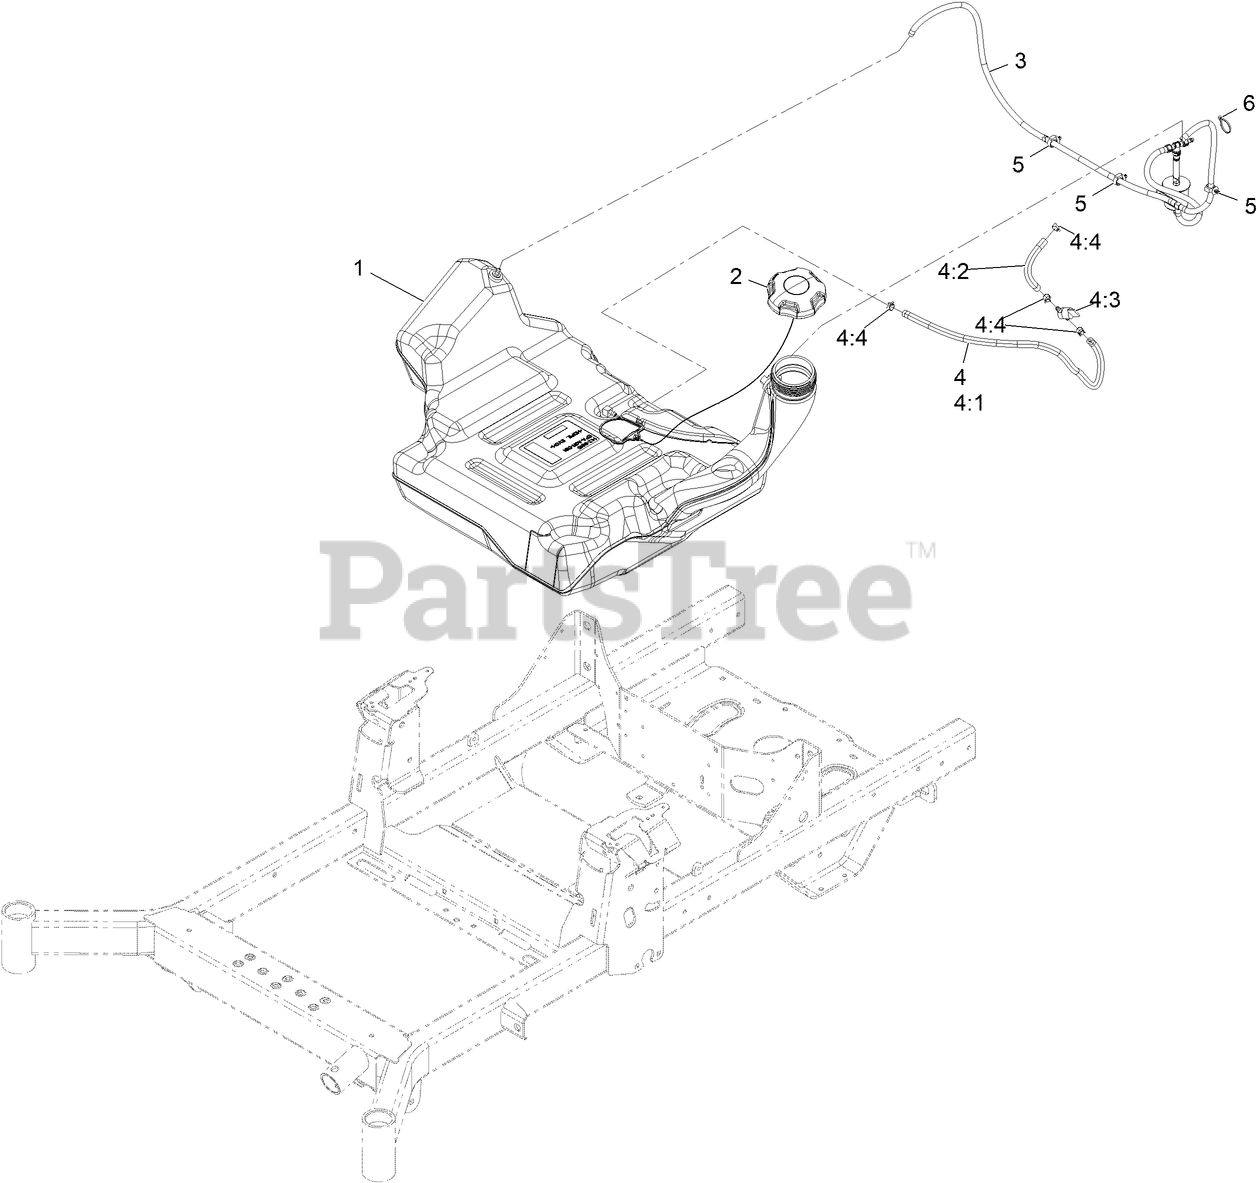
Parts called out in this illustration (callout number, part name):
1	ASM-FUEL TANK
2	CAP-FUEL, RATCHETING
3	VENT HOSE ASM
4	FUEL HOSE ASM
4:1	HOSE-FUEL
4:2	HOSE-FUEL
4:3	VALVE-FUEL
4:4	CLAMP-HOSE
6	TIE-CABLE
